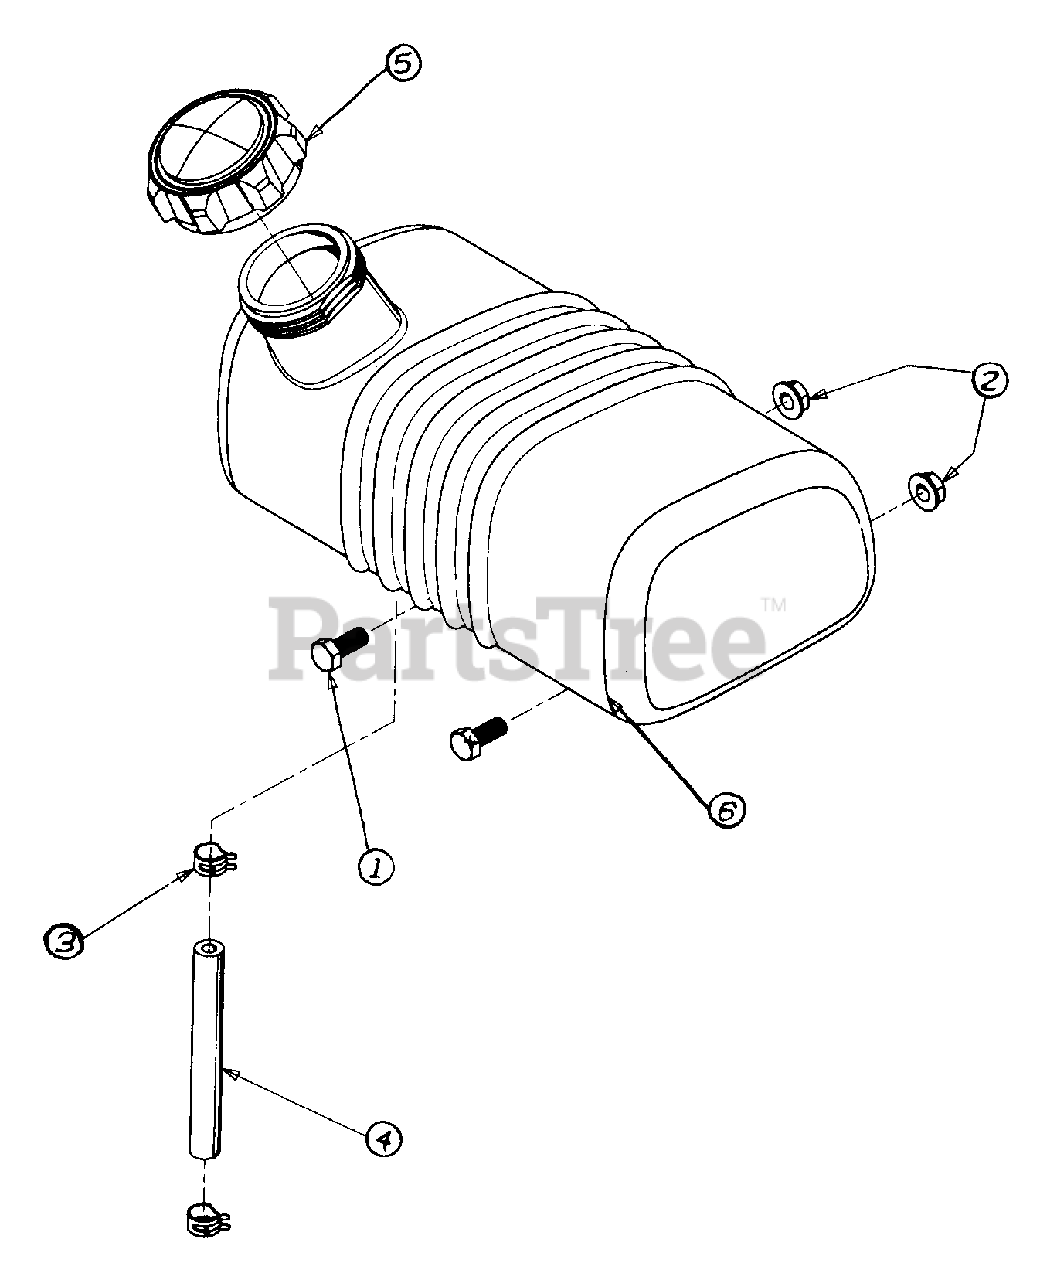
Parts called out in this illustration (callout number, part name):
2	NUT - HEX LOCK FLANGE
3	CLAMP - HOSE
4	HOSE - FUEL LINE 8"
5	CAP - FUEL
6	TANK - FUEL 1 GALLON
